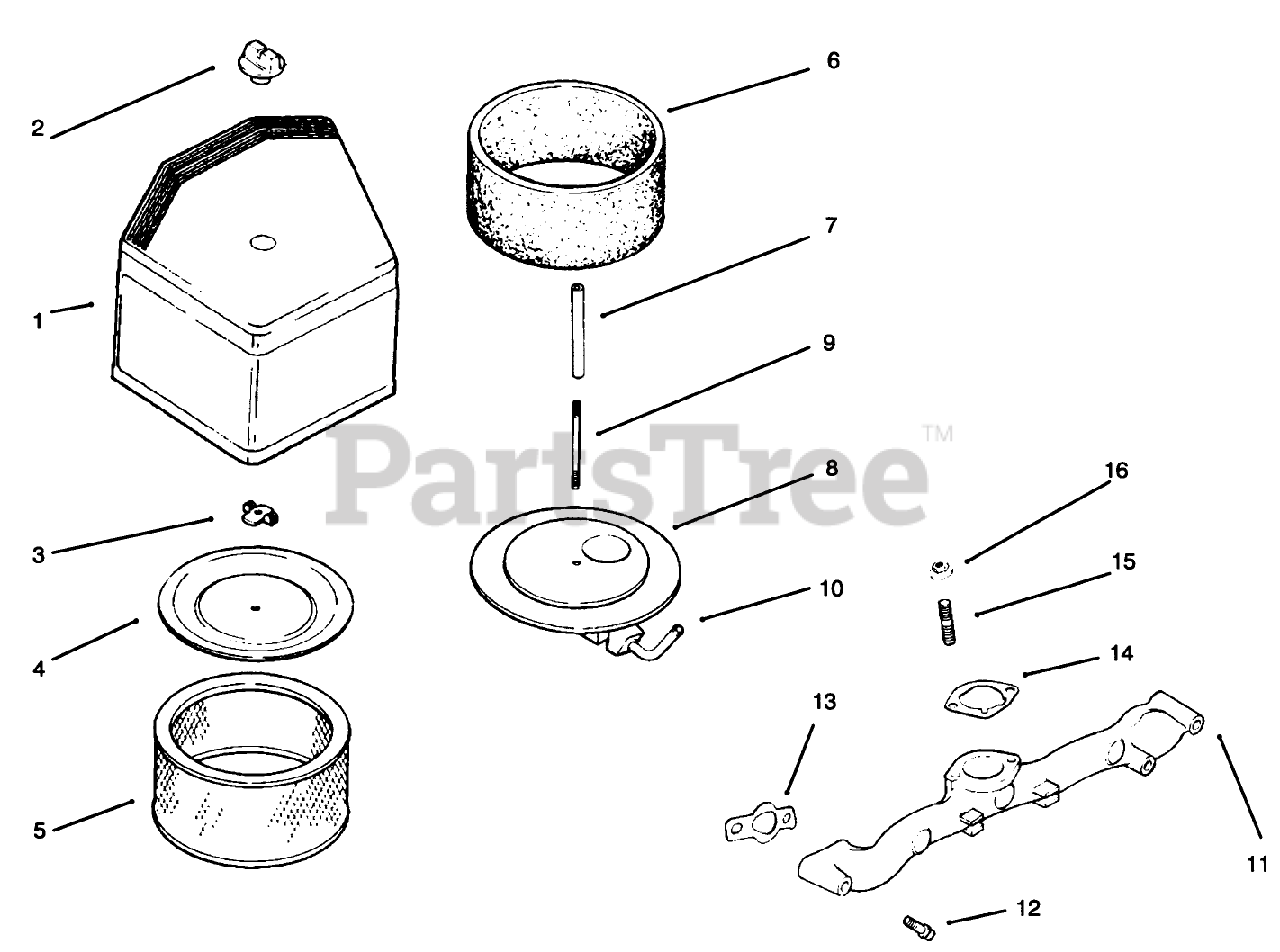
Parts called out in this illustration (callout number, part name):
1	Kit-Air Cleaner Cover (Incl. Ref.# 2)
2	Knob-Cover
3	Nut-Wing
4	Cover-Element
5	Element
6	Element
8	Elbow-Air Cleaner (Incl. Ref. # 9-10)
10	Fitting
11	Manifold-Intake (Only On: 72103)
13	Gasket-Intake Manifold
14	Gasket-A/C Base (Only On: 72103, 72083)
